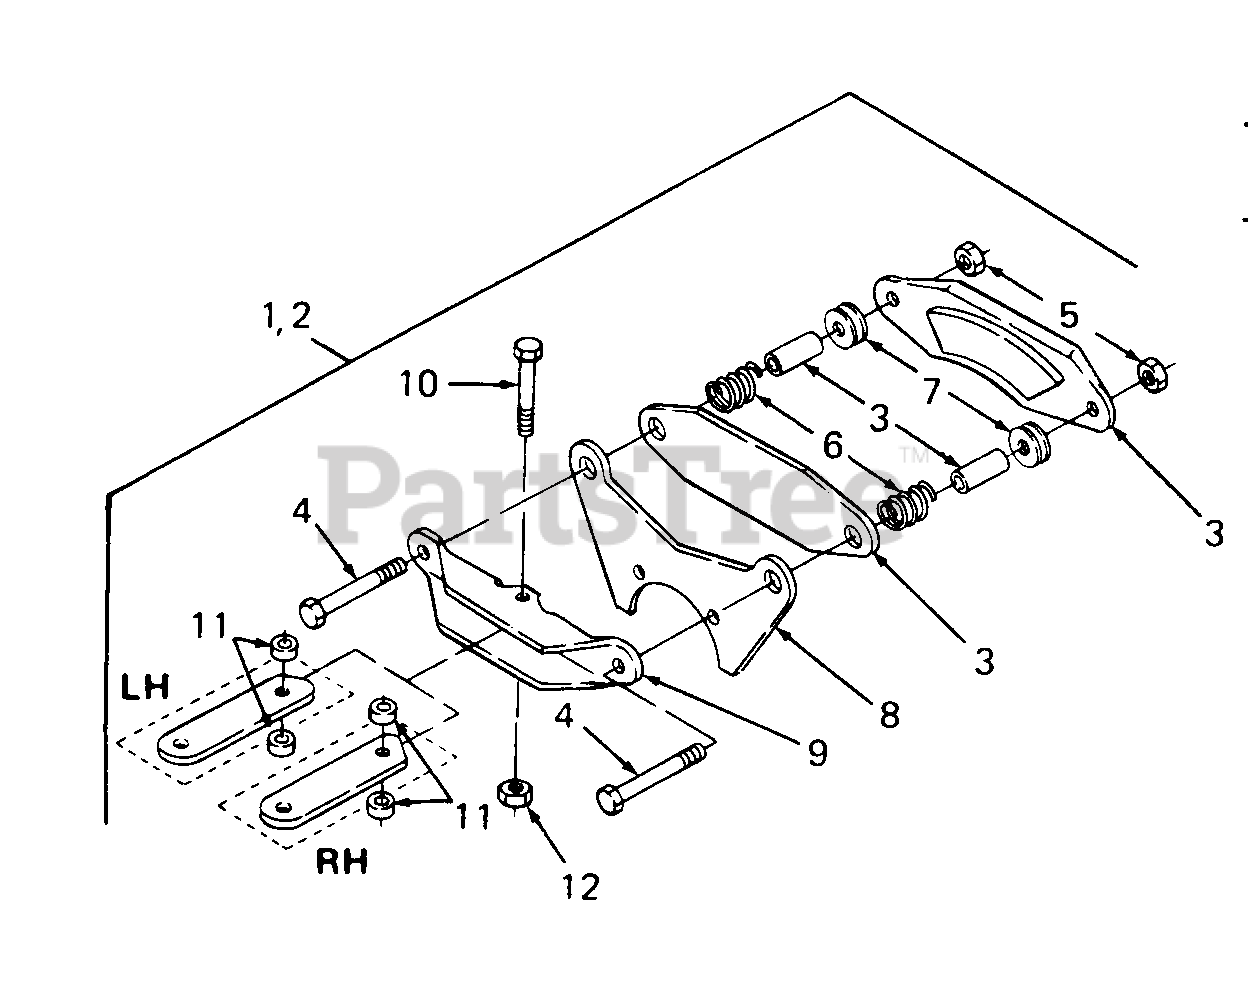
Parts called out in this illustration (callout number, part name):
1	Brake Kit, RH Caliper
2	Brake Kit, LH Caliper
3	Puck Kit, Brake
4	Screw, Hex Cap, 3/8-24 X 2.50 Lg GR5
5	Nut, Hex Lock, 3/8-24 GR5
6	Spring, Compression
7	Washer, Flat, .390 X 1.0 X .030 Thk HDN
8	Bracket, Brake Mounting
9	Bracket Assy, Actuator
10	Screw, Shoulder
12	Nut, Hex Top Lock, 1/4-20
